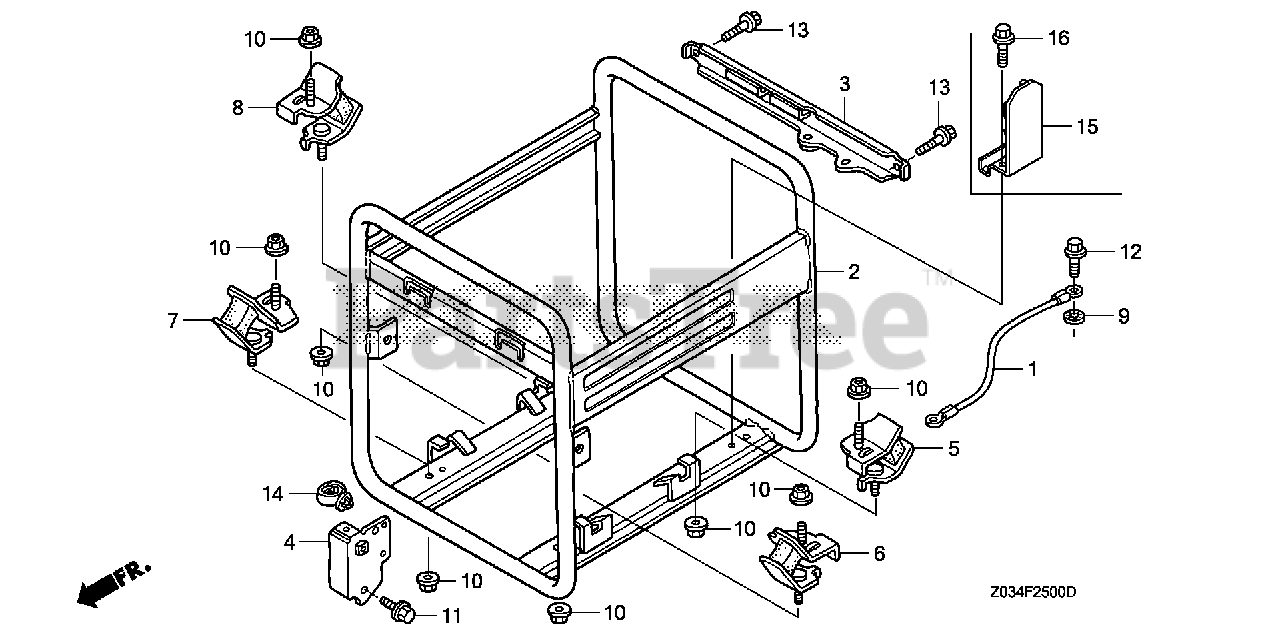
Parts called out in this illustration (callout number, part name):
1	CABLE, GROUND
2	FRAME *NH105* (MAT BLACK)
3	STAY, FUEL TANK BAR *NH105* (MAT BLACK)
5	RUBBER, R. (LOWER)
6	RUBBER, L. FR. (LOWER)
7	RUBBER, R. RR. (LOWER)
8	RUBBER, L. RR. (LOWER)
9	WASHER, LOCK (6MM)
10	NUT, FLANGE (8MM)
12	BOLT, FLANGE (6X10)
13	BOLT, FLANGE (6X16)
